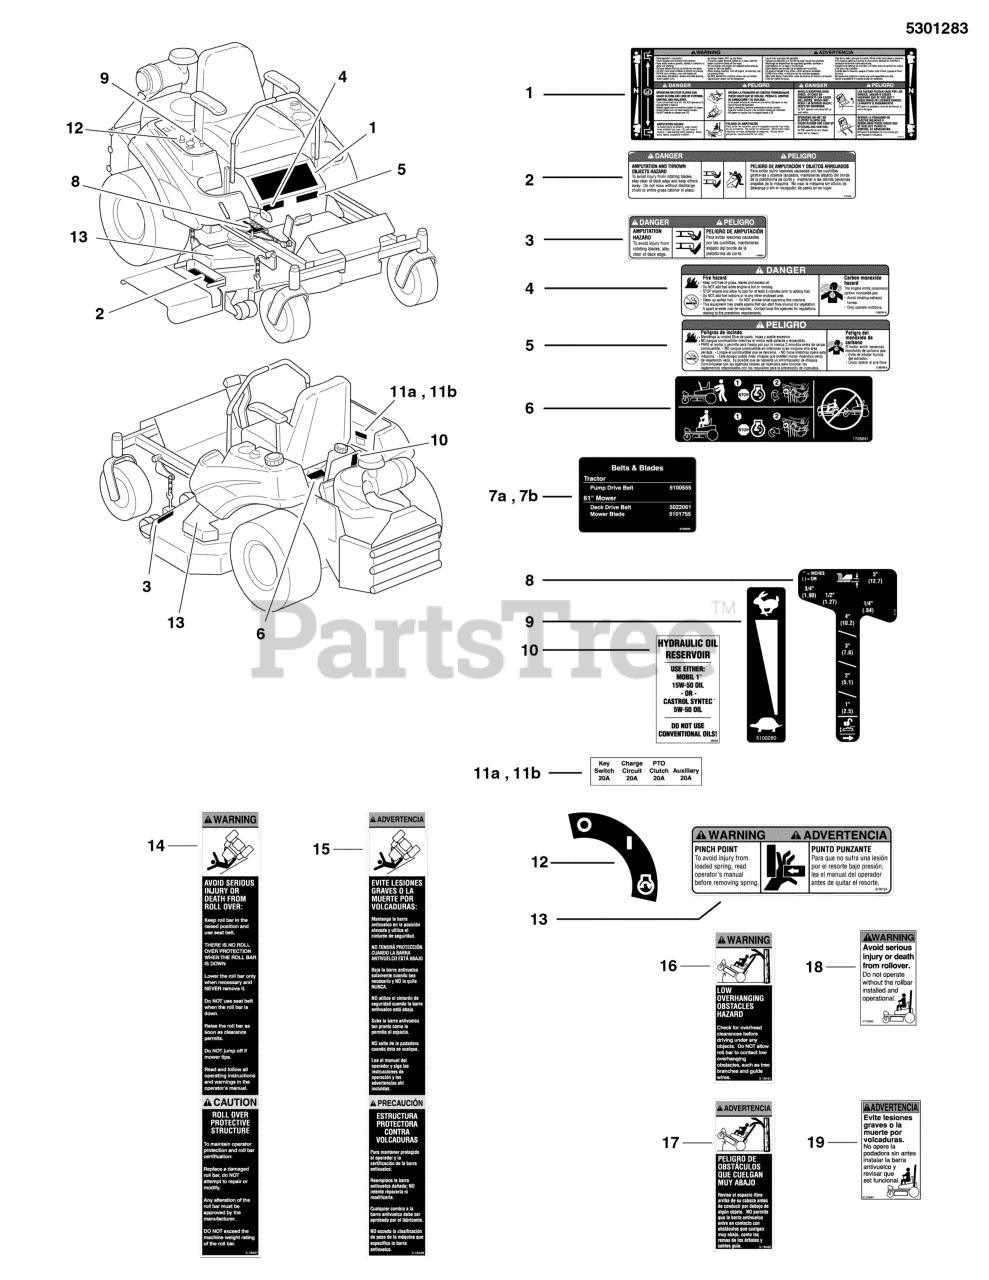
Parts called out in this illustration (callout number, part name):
1	DECAL, MAIN SAFETY
2	DECAL, DANGER, MOWER DISCHARGE,8.75X2.13
3	DECAL, DANGER, MOWER
4	DECAL, DANGER, FIRE
5	DECAL, DANGER, FIRE (SP)
6	*DECAL, CZT HYRDO RELEASE
8	DECAL-HEIGHT CITATION
9	DECAL, THROTTLE CONTROL
10	DECAL, OIL RESEVOIR
12	DECAL, IGNITION SWITCH
13	DECAL, WARNING, PINCH POINT
16	DECAL, WARNING OVERHANG, ROPS
18	DECAL, WARNING, ROLL BAR
19	DECAL, WARNING, ROLL BAR (SP)
